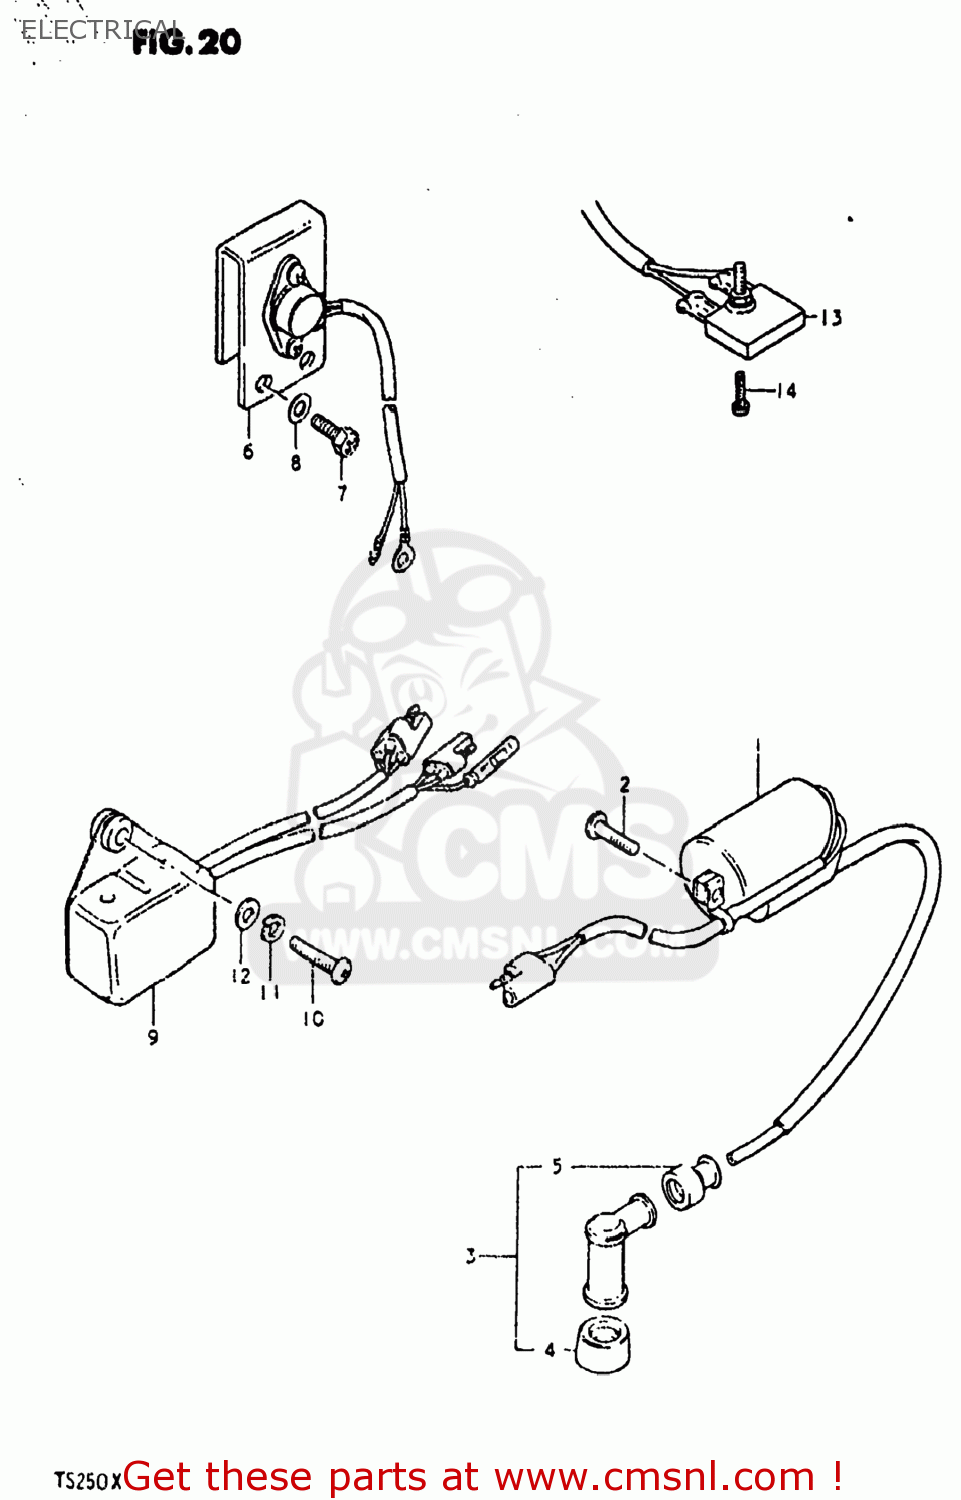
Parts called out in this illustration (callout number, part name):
1	COIL ASSY,IGNITION
2	SCREW 5X20
3	CAP,SPARK PLUG
4	SEAL,SPARK PLUG
5	SEAL,SPARK PLU
6	REGULATOR ASSEMBLY
7	SCREW(5X12)
8	WASHER
9	CDI UNIT
10	SCREW
11	LOCK WASHER
12	WASHER
13	RECTIFIER ASSEMBLY
14	SCREW
